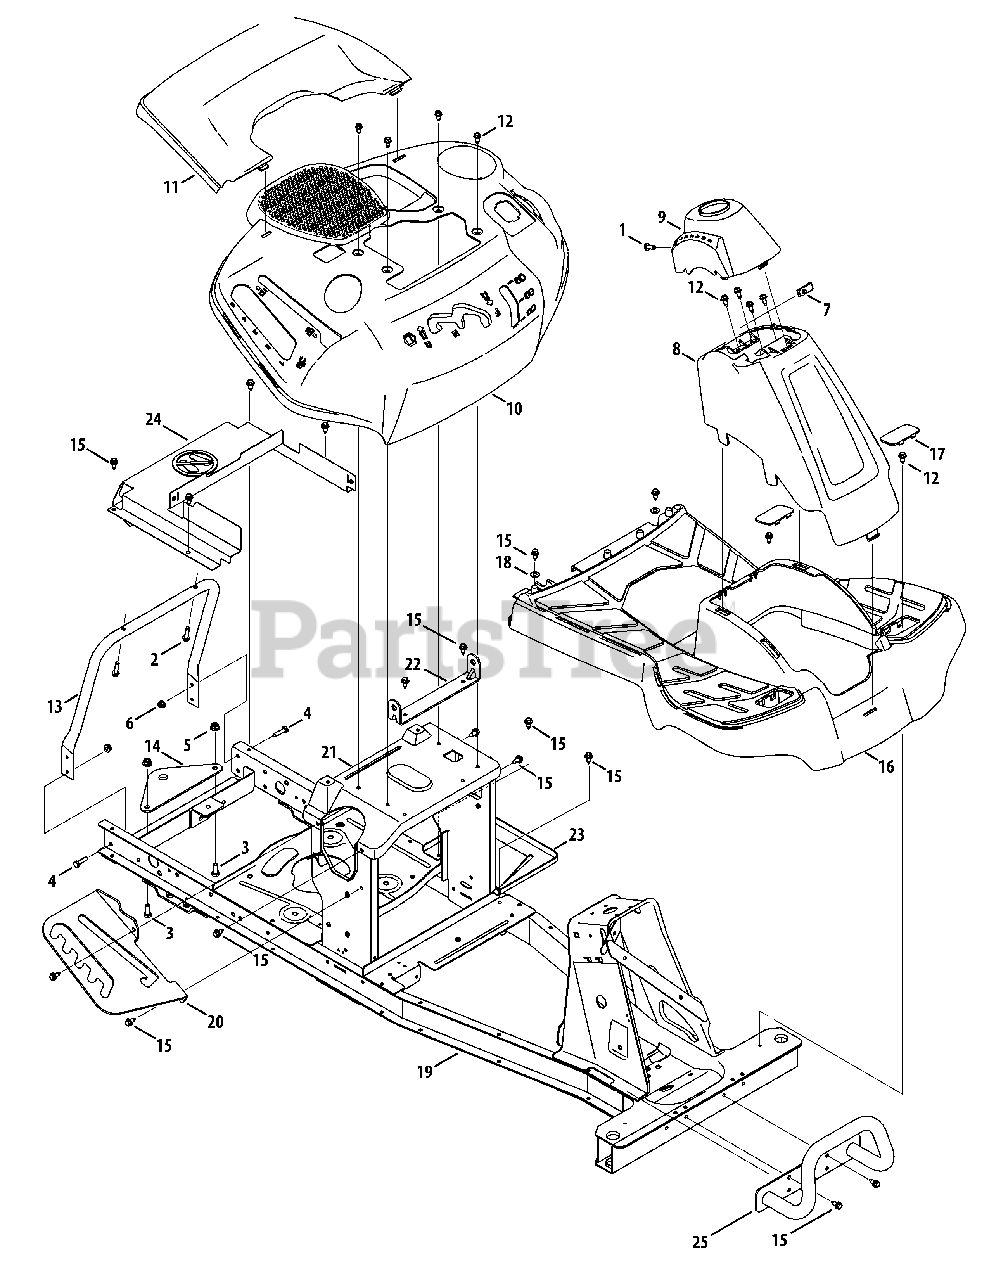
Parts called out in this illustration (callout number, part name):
1	Machine Screw, 1/4-20x0.750
2	Hex Screw, 1/4-15x1.000
3	Hex Head Screw, 5/16-18x.75
4	Hex Head Screw, 1/4-20x.75
5	Flange Locknut, 5/16-18
6	Flange Locknut, 1/4-20
7	U-type Speed Nut, 1/4-20
8	Column Cover
9	Steering Column Cap
10	Fender
11	Rear Cover
12	Shoulder Screw, .368 X.113X1/4-20
13	Rear Cover Support Tube
14	Hitch Plate
15	Tap Screw, 1/4-20x.625
16	Running Board
17	Running Board Plug
18	Flat Washer, .250 x .630 x .052
19	Frame Assembly
20	Deck Lift Index Bracket
22	Seat Pivot Bracket
23	Battery Tray
24	Top Rear Drive Cover
